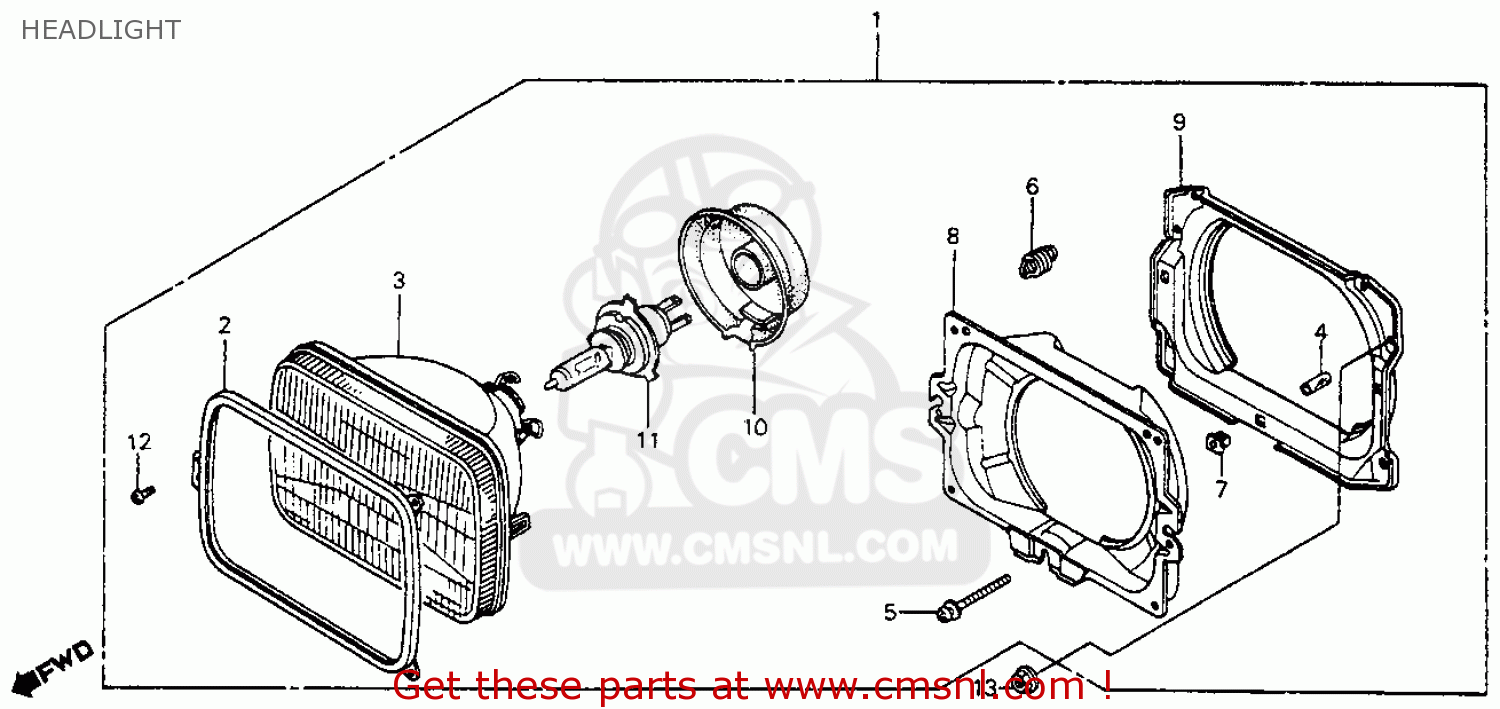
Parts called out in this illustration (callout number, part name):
1	HEAD LIGHT ASSY.
2	RING,RETAINING
3	HEADLIGHT UNIT
4	TUBE,SCREW
5	SCREW,ADJUSTER
6	SPRING,ADJUST
7	NUT NYLON CAP
8	RING, MOUNTING (1)
9	MOUNTING RING (2)
10	COVER RUBBER
11	BULB,HEADLIGHT
12	SCREW PAN,4X8
13	NUT,FLANGE,6MM
